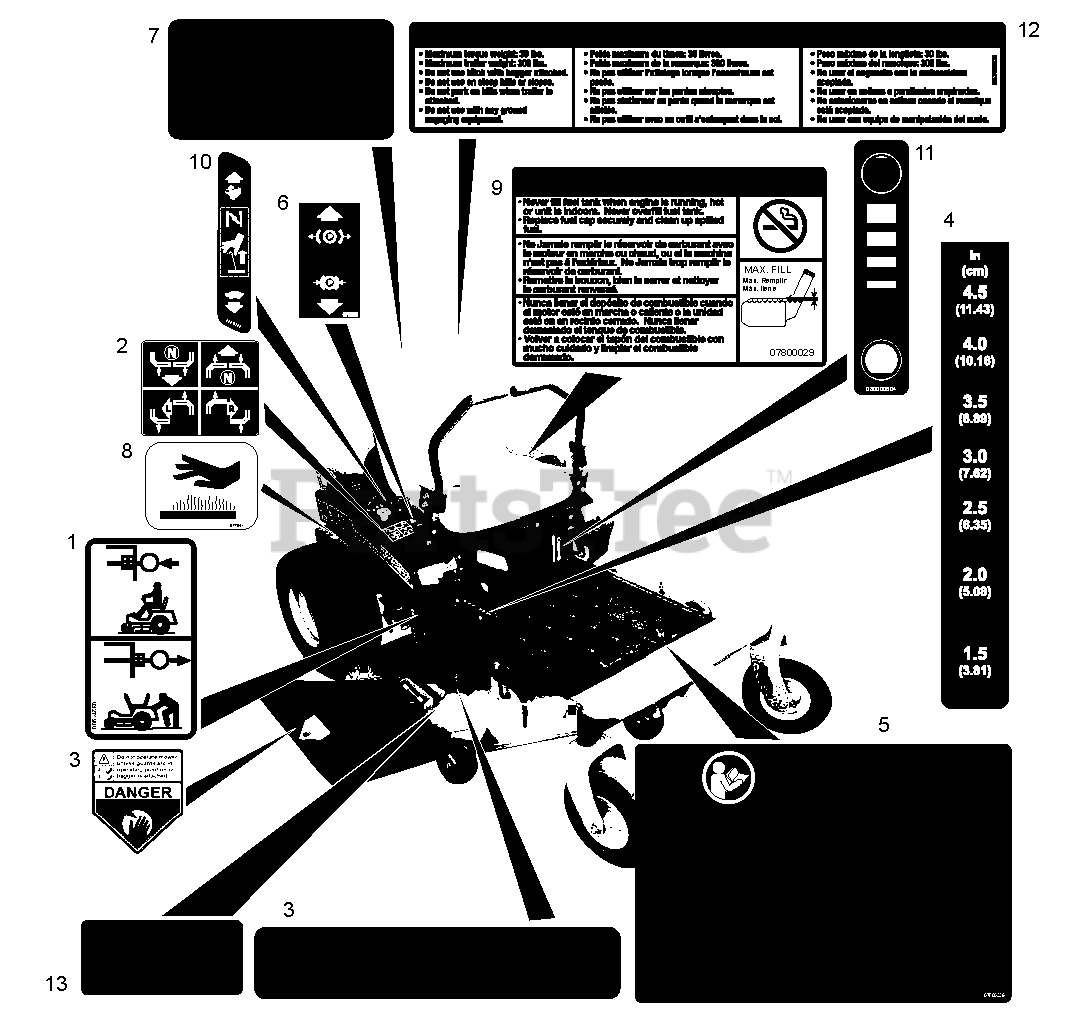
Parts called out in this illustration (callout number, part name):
1	Decal, Transmission Disconnect
2	Decal, Instructional Steering
3	Decal, Safety – Mower Deck
4	Decal, Cut Height
5	Decal, Safety – Main
6	Decal, Parking Brake Lever
7	Decal, Safety – Guarding
8	Decal, Hot Surface
9	Decal, Fuel Warning
10	Decal, Throttle Control (915146, 168)
11	Decal, Fuel Level
12	Decal, Trailer Hitch (915148, 150, 170)
13	Decal, Safety – Deck Guarding
